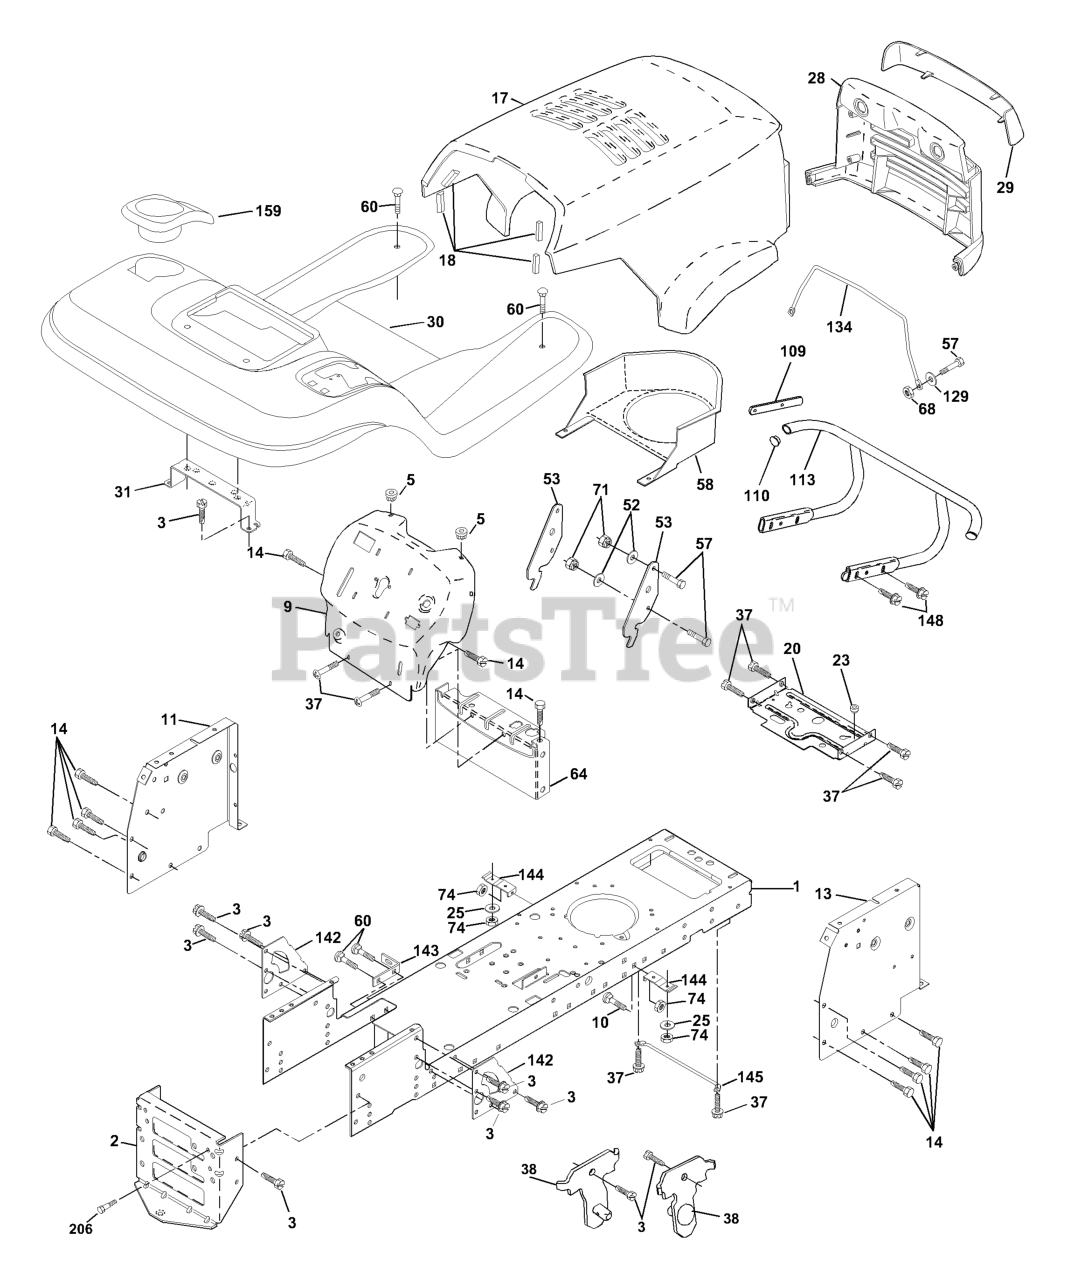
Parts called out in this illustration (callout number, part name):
2	DRAWBAR
3	SCREW 3/8-16X3/4
5	BUMPER.RUBBER.HOOD
9	DASH, SILKSCREENED
10	BOLT D
11	PANEL DASH LH
13	DASH PANEL RH
14	SCREW LT
17	HOOD
18	BUMPER HOOD T
20	PLATE MTG
23	BUSHING.SNAP.NYL.BLK.
25	WASHER
26	NUT
28	GRILL
29	LENS
30	FENDER FOOTREST STLT PNT
31	BRACKET.SUPPORT.FENDER
37	Screw Thdrol 6/16-18 x 1/2 TYT
38	BRACKET
52	WASHER
53	BRACKET PNT PICK OFF LT/PL
57	BOLT
58	AIR DUCT P/L/LT
60	Bolt Rdhd Sqnk 3/8-16unc x 3/4
64	DASH LOWER
68	NUT
71	NUT.CROWNLOCK.1/4
109	BUMPER BRACKET
110	PLUG PLASTIC
113	BUMPER ASM.
129	WASHER
134	ROD SUPPORT HOOD LT/PL HUS.
142	PLATE
143	BRACKET, SWAY BAR
144	BRACKET FOOTREST
145	ROD PIVOT CHASSIS/HOOD
148	SCREW.3/8-16
159	CUPHOLDER
206	SHOULDER BOLT 5/16-18TT
